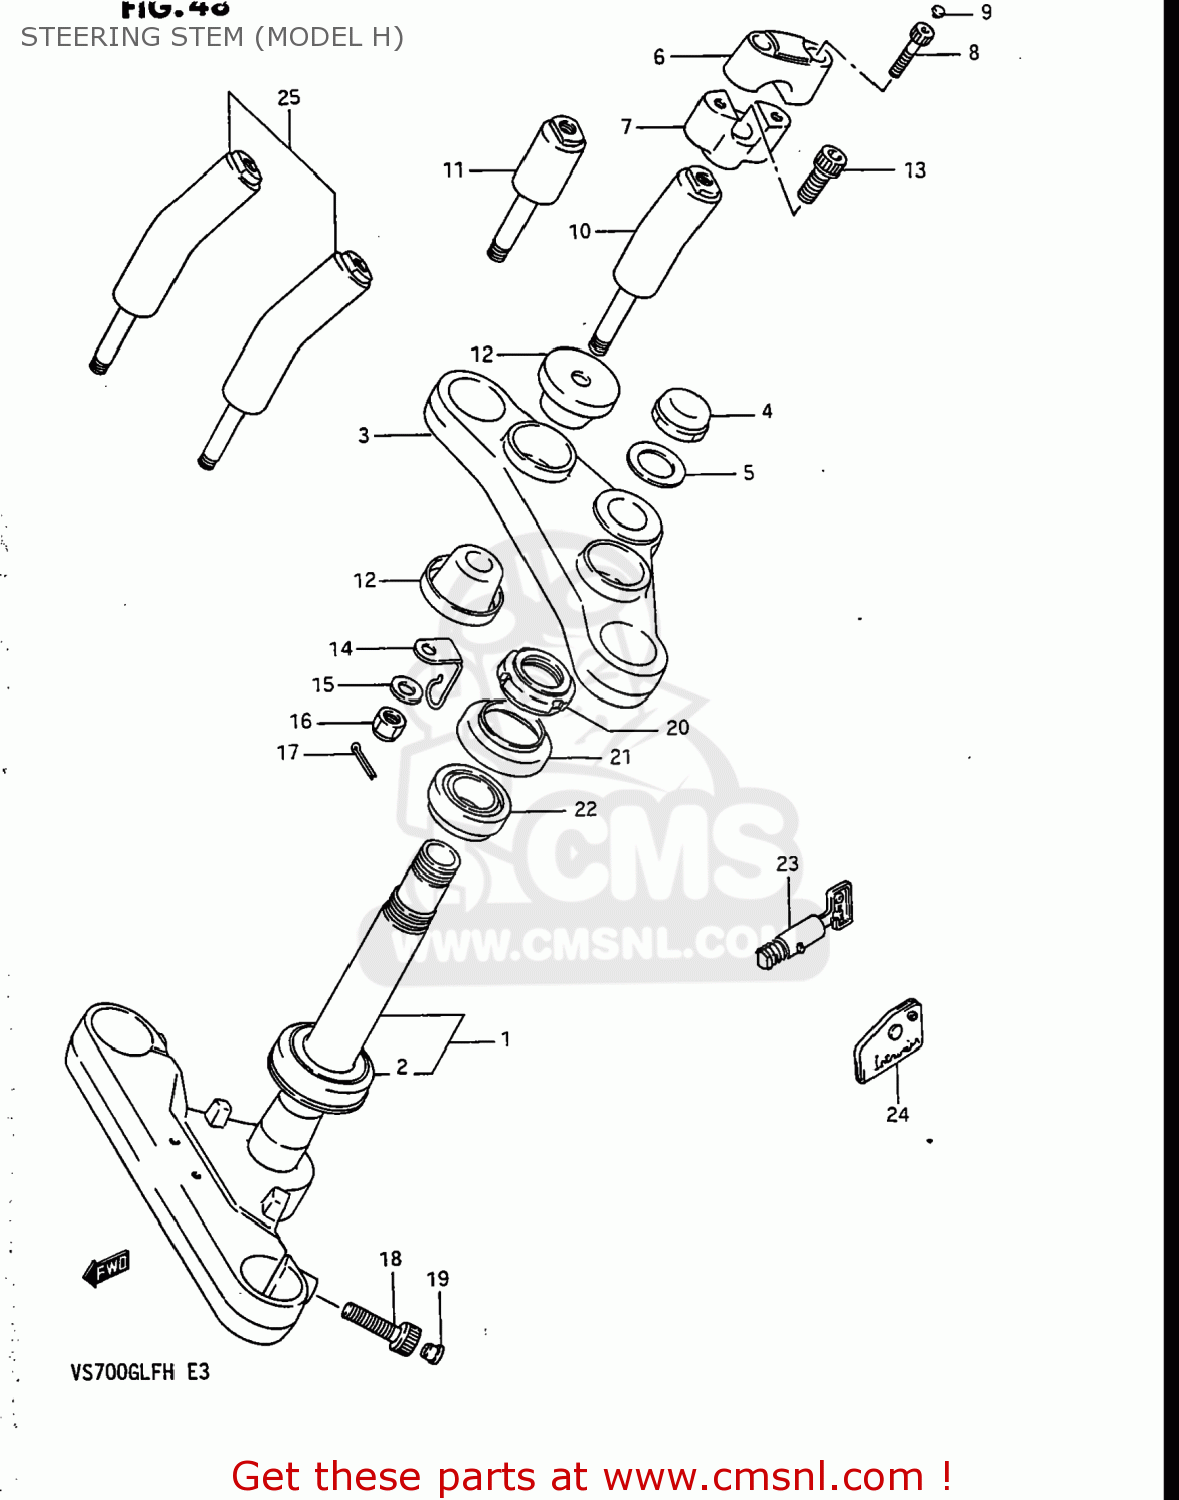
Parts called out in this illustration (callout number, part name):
1	STEM,STEERING
2	BEARING
3	STEM HEAD,STEERING
4	NUT,CAP
5	WASHER
6	HOLDER,HANDLE UPR
7	HOLDER,HANDLE LWR
8	BOLT, REAR (8X30)
9	CAP(OD:14.5)
10	STAY,HANDLE
11	STAY,HANDLE
12	CUSHION
13	BOLT
14	CLAMP,SPEEDOMETER CABLE
15	WASHER
16	NUT
17	PIN 20X20
18	BOLT,STEERING STEM HEAD
19	CAP(OD:12)
20	NUT,STEERING STEM(25X44X10)
21	DUST SEAL,STEERING,UPPER
22	TAPER,ROLLER BEARING
23	LOCK SET,STEERING
24	CASE,STEERING KEY
25	STAY SET,HANDLE
